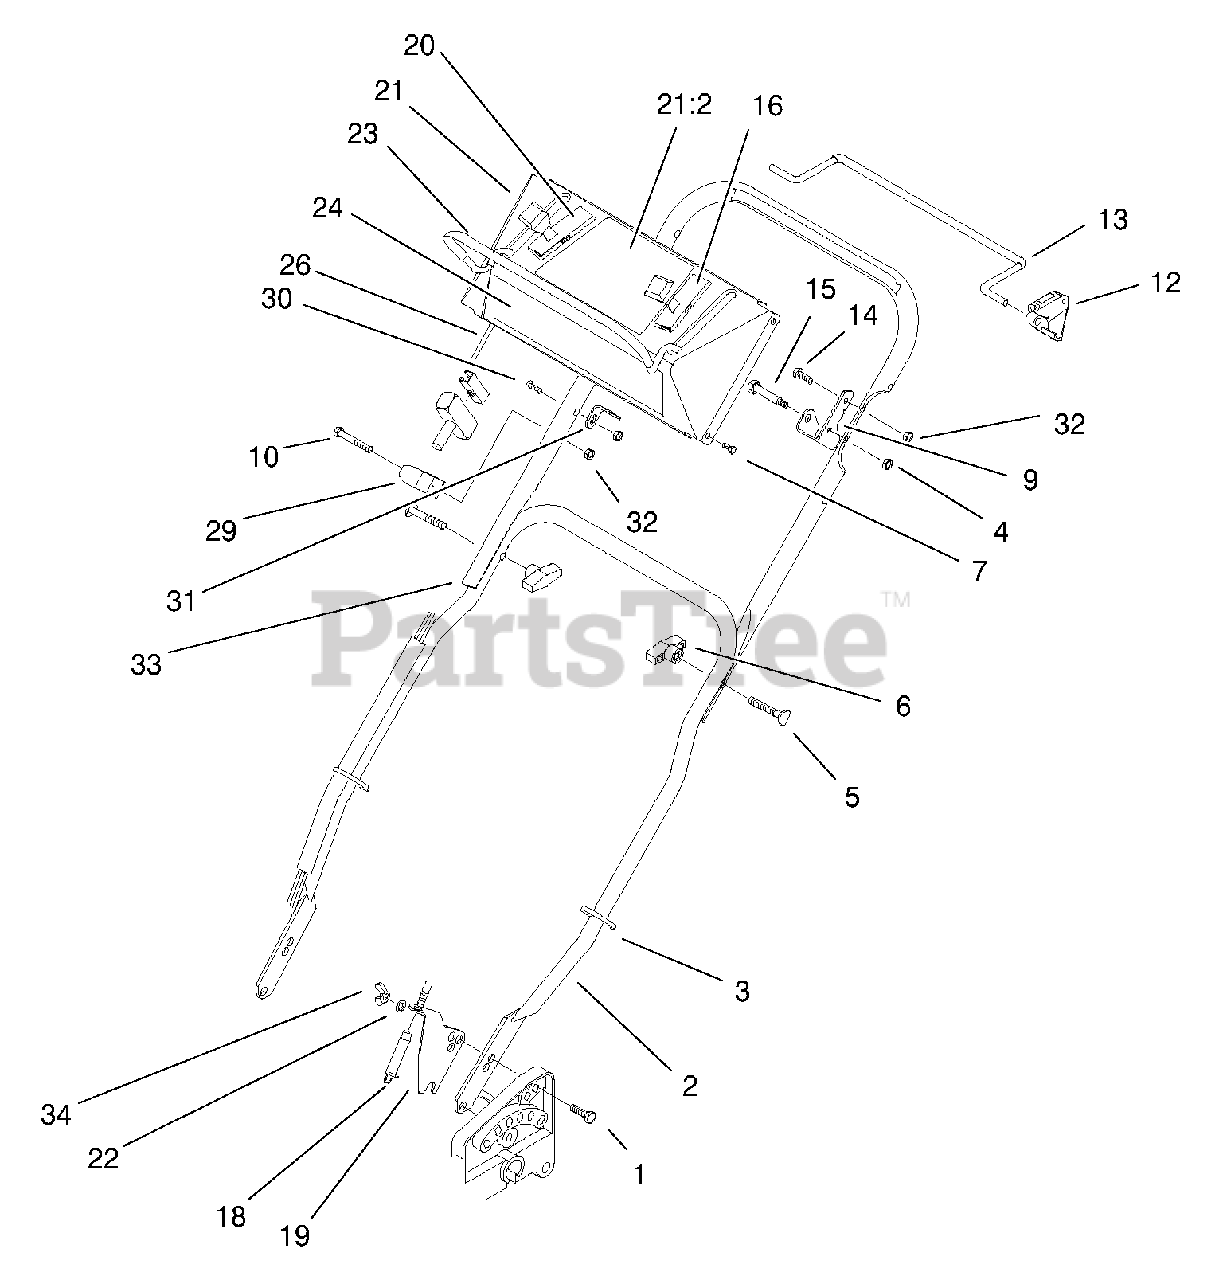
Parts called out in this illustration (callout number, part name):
1	Screw-CARR
2	Handle-Lower
3	Tie Strap
4	Nut-Lock, NI
6	Knob-Handle
9	Bracket-Stop, Bail
10	Screw-HH
12	Stop-Pivot
13	Bail-Control
14	Screw-HH
16	Control ASM-Throttle
18	Cable-Traction
19	Bracket-Traction Cable
20	Control ASM-Ground Speed
21	Panel w/Decal
21:2	Decal-Control Panel
22	Washer-Lock
23	Bail-Engine Control
24	Decal-Panel Sp
26	Cable ASM-Brake
29	Rope-Guide
30	Screw-Handle
31	Bracket-Anchor, Cable
32	Nut-Lock, NI
33	Handle-Upper
